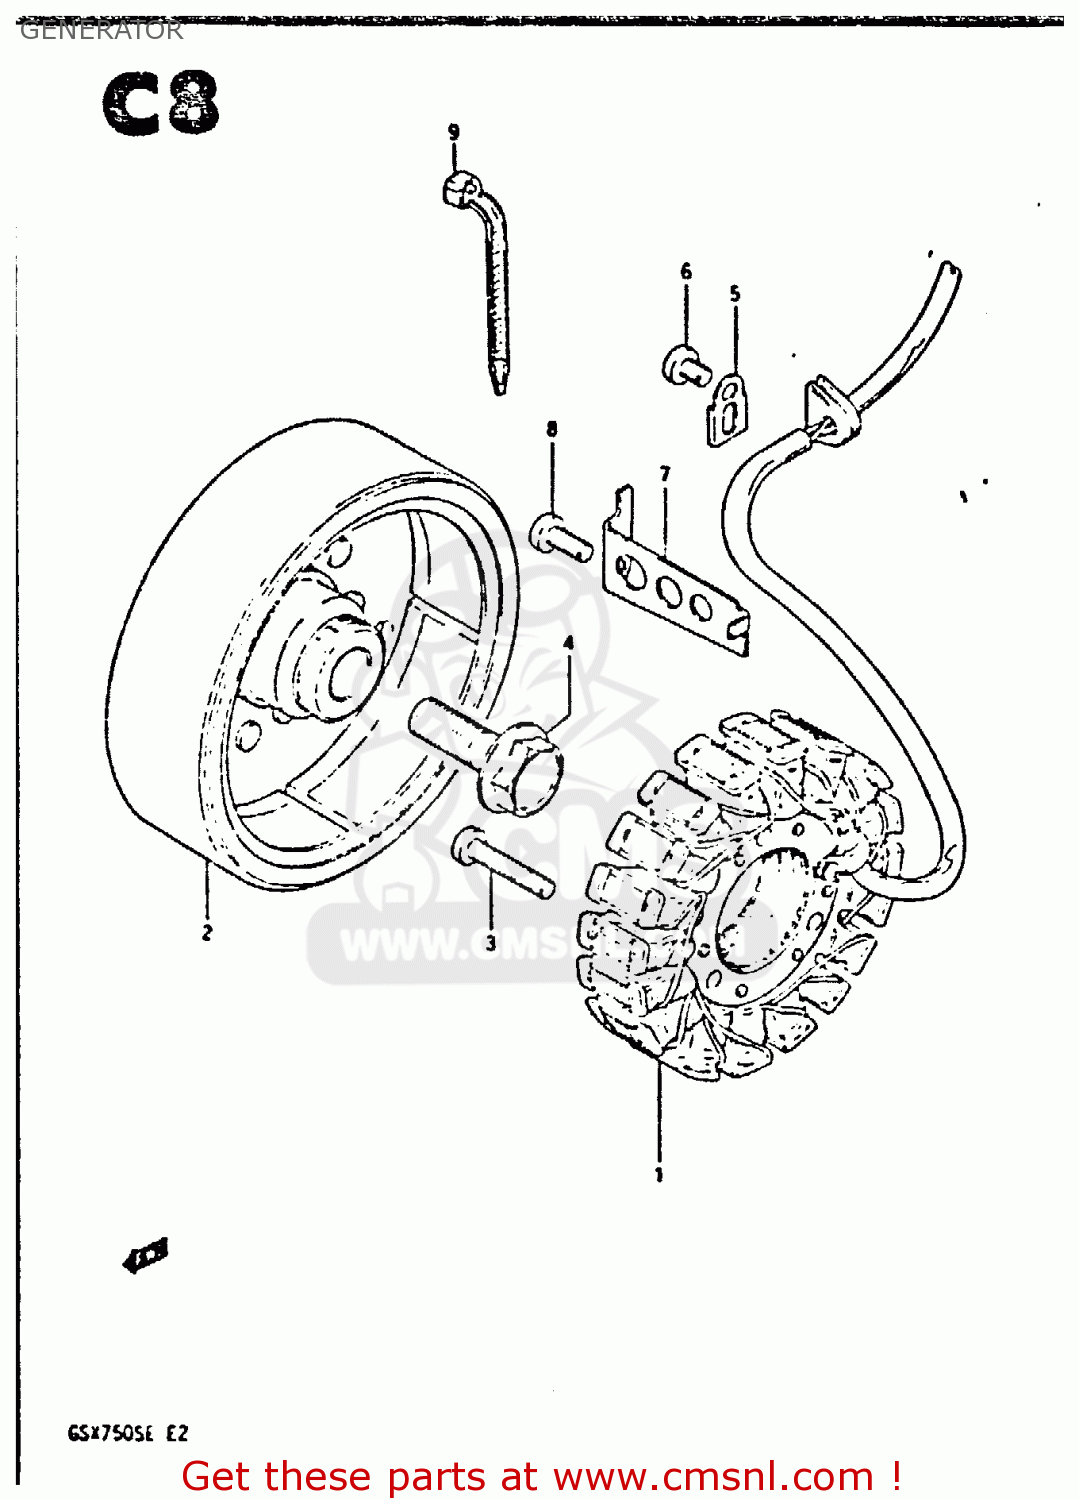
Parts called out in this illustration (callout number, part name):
1	STARTER ASSY
2	ROTOR ASSEMBLY
3	SCREW 6X30
4	BOLT(14X43)
5	CLAMP,GENERATOR LEAD WIRE
6	SCREW
7	CLAMP,GENERATOR LEAD WIRE
8	SCREW
9	CLAMP(L:95)
